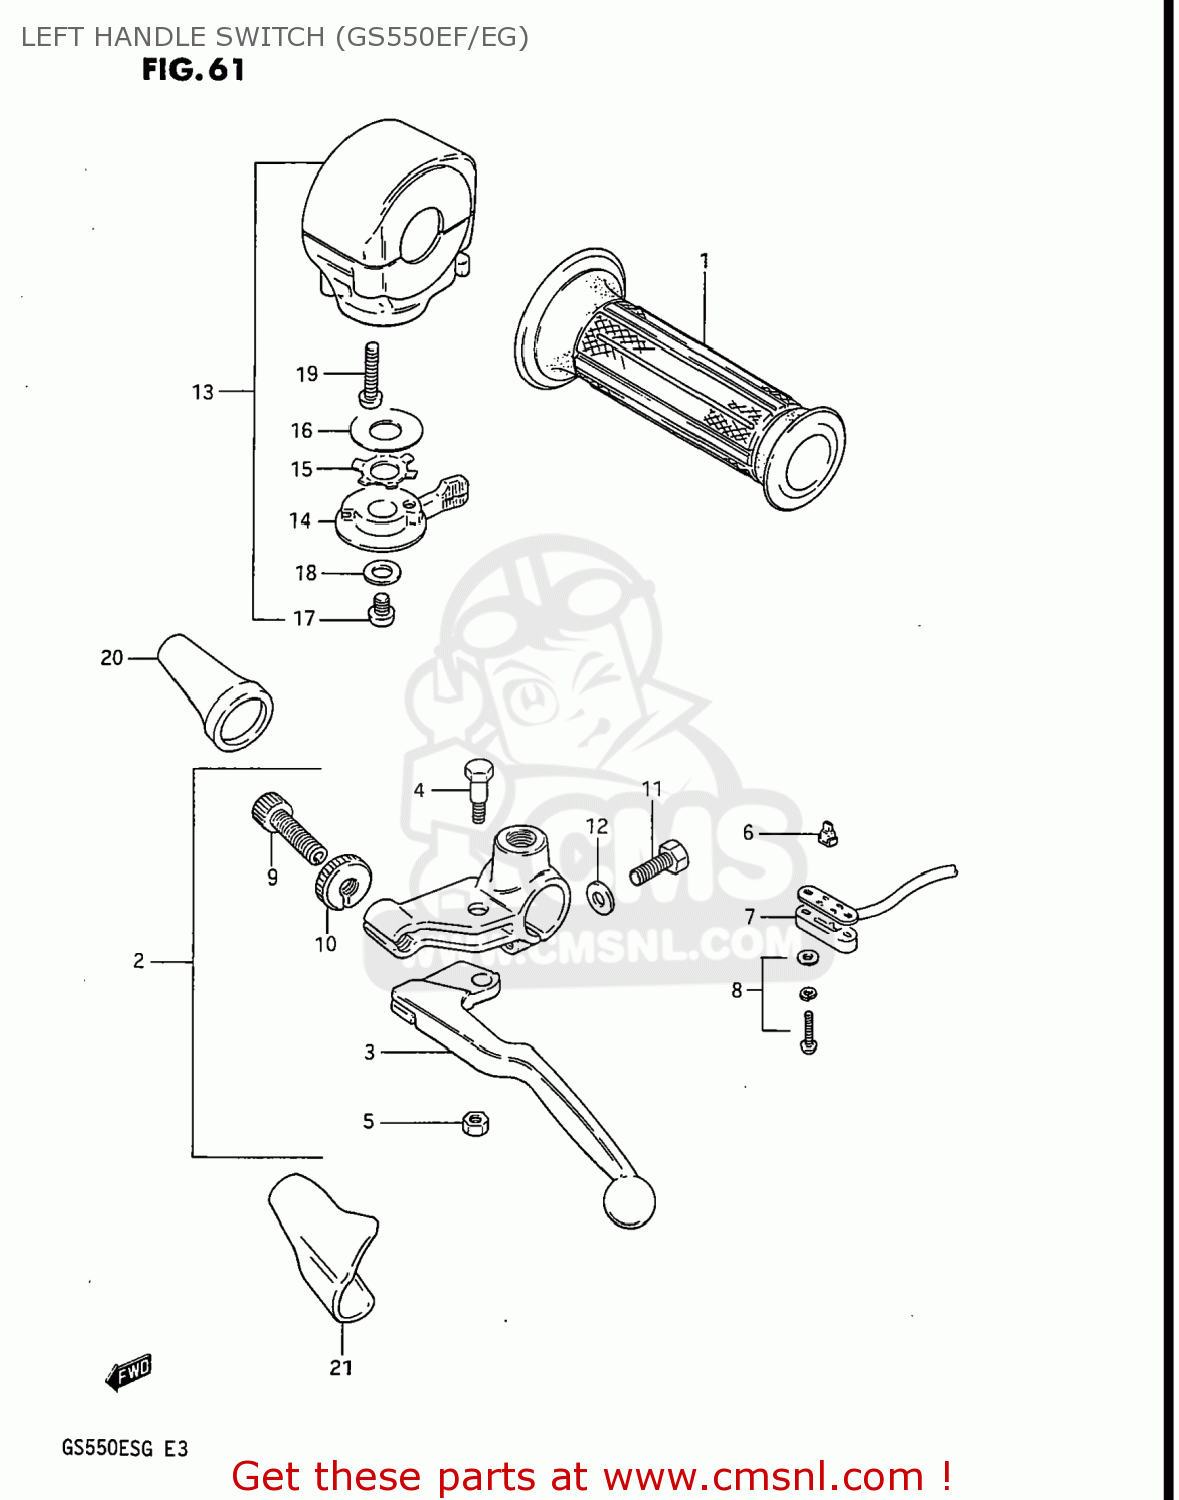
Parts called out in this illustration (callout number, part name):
1	GRIP,L
2	LEVER ASSY,CLUTCH
3	LEVER,CLUTCH
4	BOLT,LEVER PIVOT
5	NUT
6	CONTACT,SWITCH
7	COVER,FR BK TERMINAL BASE
8	SCREW
9	ADJUSTER,CABLE
10	NUT,CABLE ADJUSTER LOCK
11	BOLT
12	WASHER
13	SWITCH ASSEMBLY,HANDLE,LEFT
14	LEVER,STARTER
15	WASHER
16	WASHER
17	SCREW
18	WASHER
19	SCREW
20	BOOT,CLUTCH CABLE
21	COVER,CLUTCH LEVER
